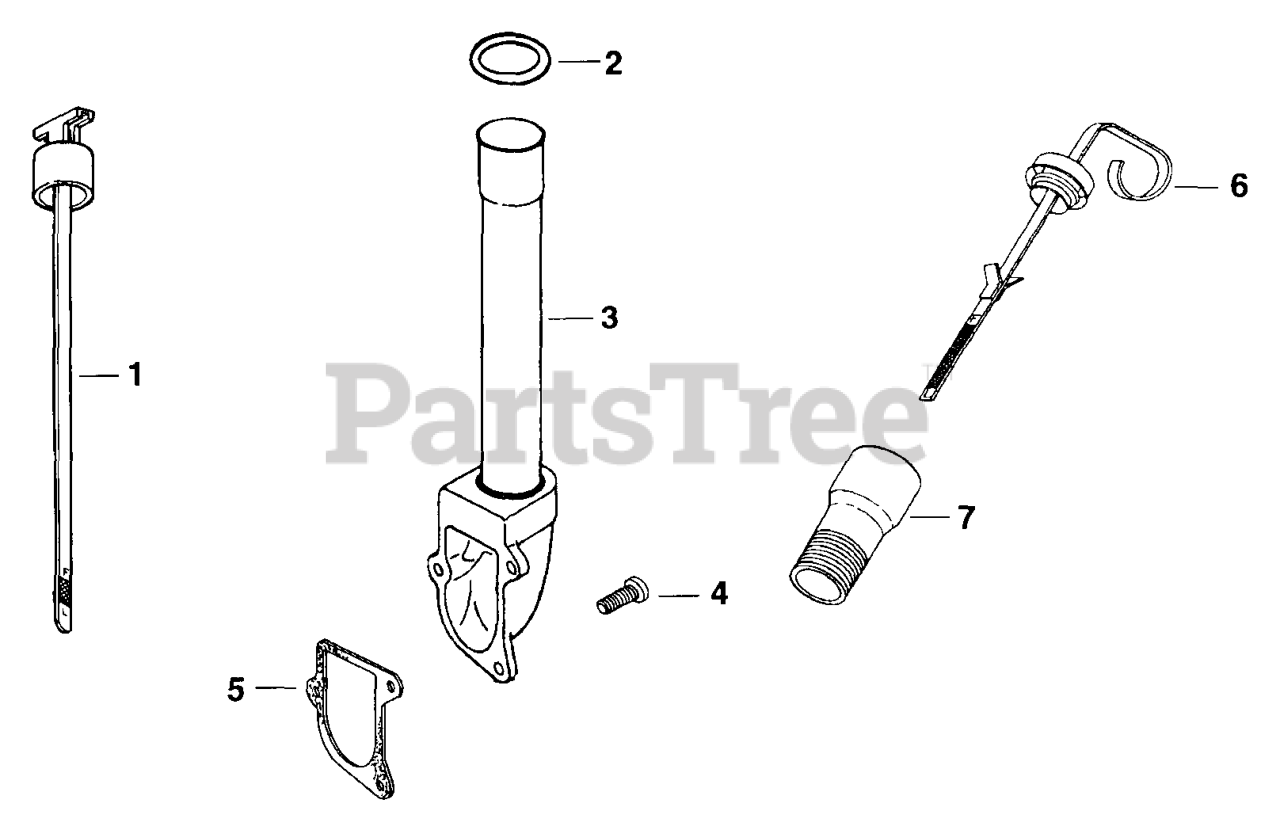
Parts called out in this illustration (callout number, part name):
1	DIPSTICK - DISCONTINUED
4	SCREW - DISCONTINUED
5	GASKET, OIL FILL ADAPTER
